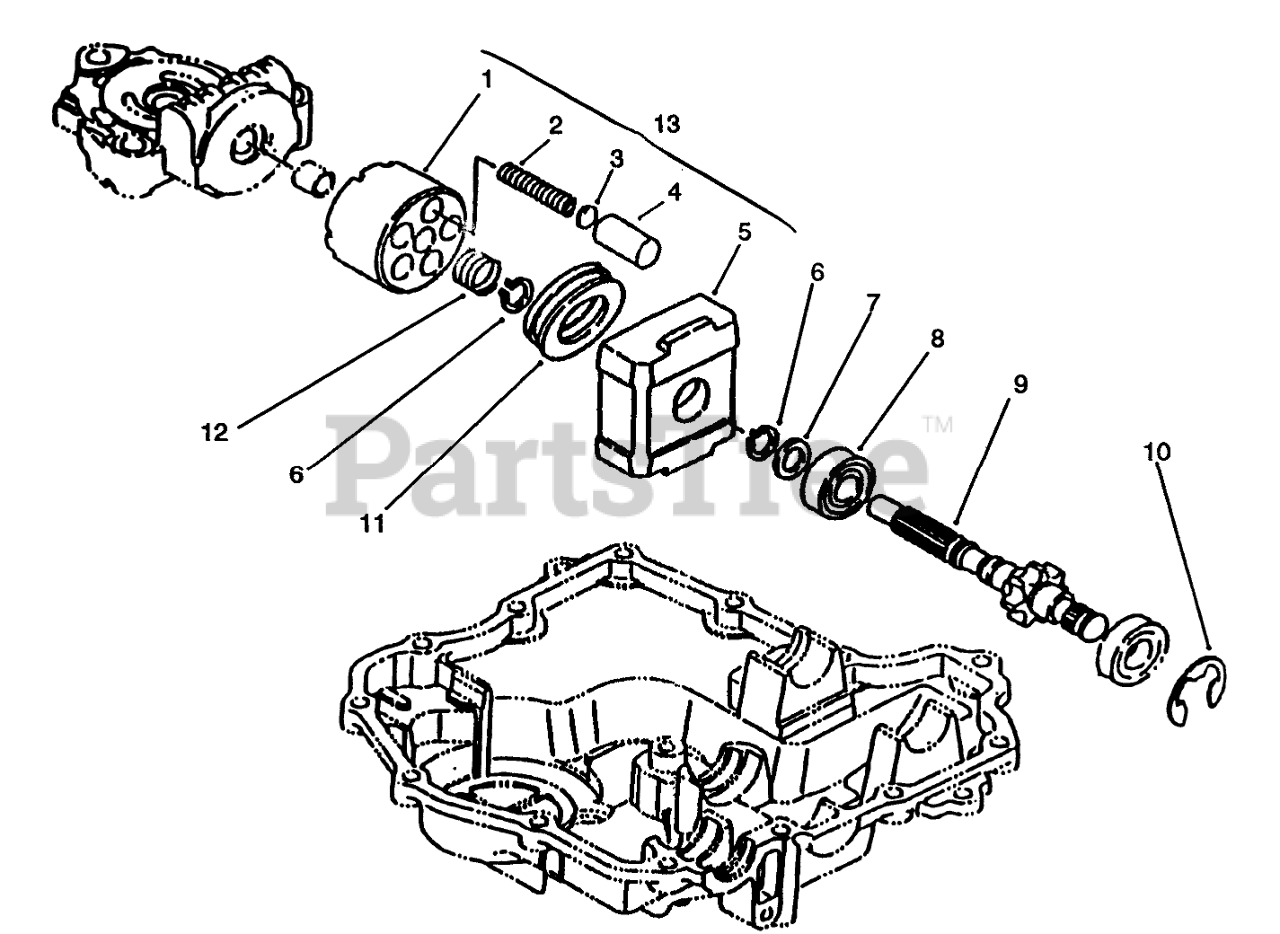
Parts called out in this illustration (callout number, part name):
5	Housing (Only On: 72083, 72043, 72103, 72063)
6	Ring-Snap (Only On: 72083, 72043, 72103, 72063)
7	Washer (Only On: 72083, 72043, 72103, 72063)
8	Bearing-Ball (Only On: 72083, 72043, 72103, 72063)
9	Shaft-Motor (Only On: 72083, 72043, 72103, 72063)
10	E Ring (Only On: 72083, 72043, 72103, 72063)
11	Bearing-Thrust (Only On: 72083, 72043, 72103, 72063)
13	Cylinder ASM INC 6-9 (Only On: 72083, 72043, 72103, 72063)
